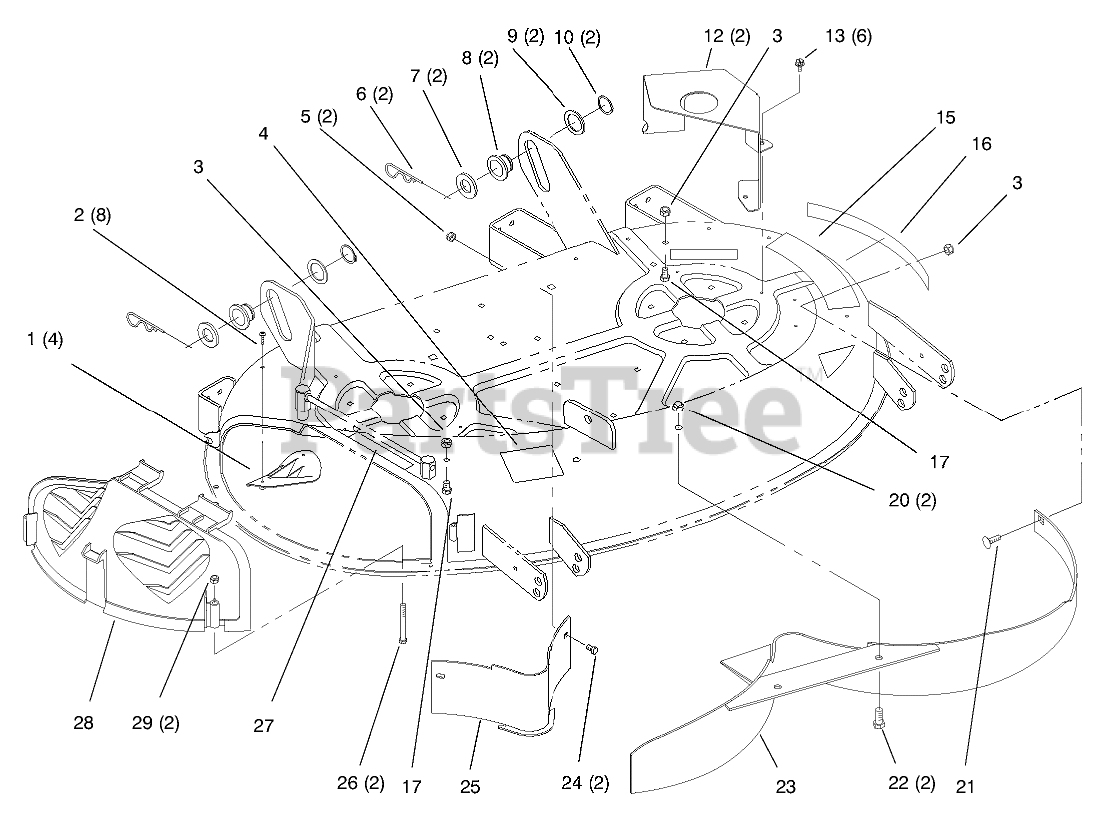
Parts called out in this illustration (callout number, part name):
1	PLATE-KICKER
2	SCREW-PPH
3	NUT-LOCK, NI
4	Decal-Routing
5	NUT-LOCK, NI
6	PIN-HAIR
7	WASHER-FLAT
8	ROLLER-LIFT
9	WASHER
10	RING-RETAINING
12	COVER-BELT
13	SCREW-HWHTF
15	Decal-Dange
15	DECAL - DANGER
16	DECAL-RECYCLER DECK 38"
17	SCREW-HH
20	NUT-LOCK, NI
21	SCREW-CARR
21	BOLT-CARR
22	SCREW-HH
23	BAFFLE ASM
24	SCREW-HH
25	BAFFLE ASM
26	SCREW-HH
27	DECAL-CAUTION
28	COVER-RECYCLER
29	NUT-CAP
